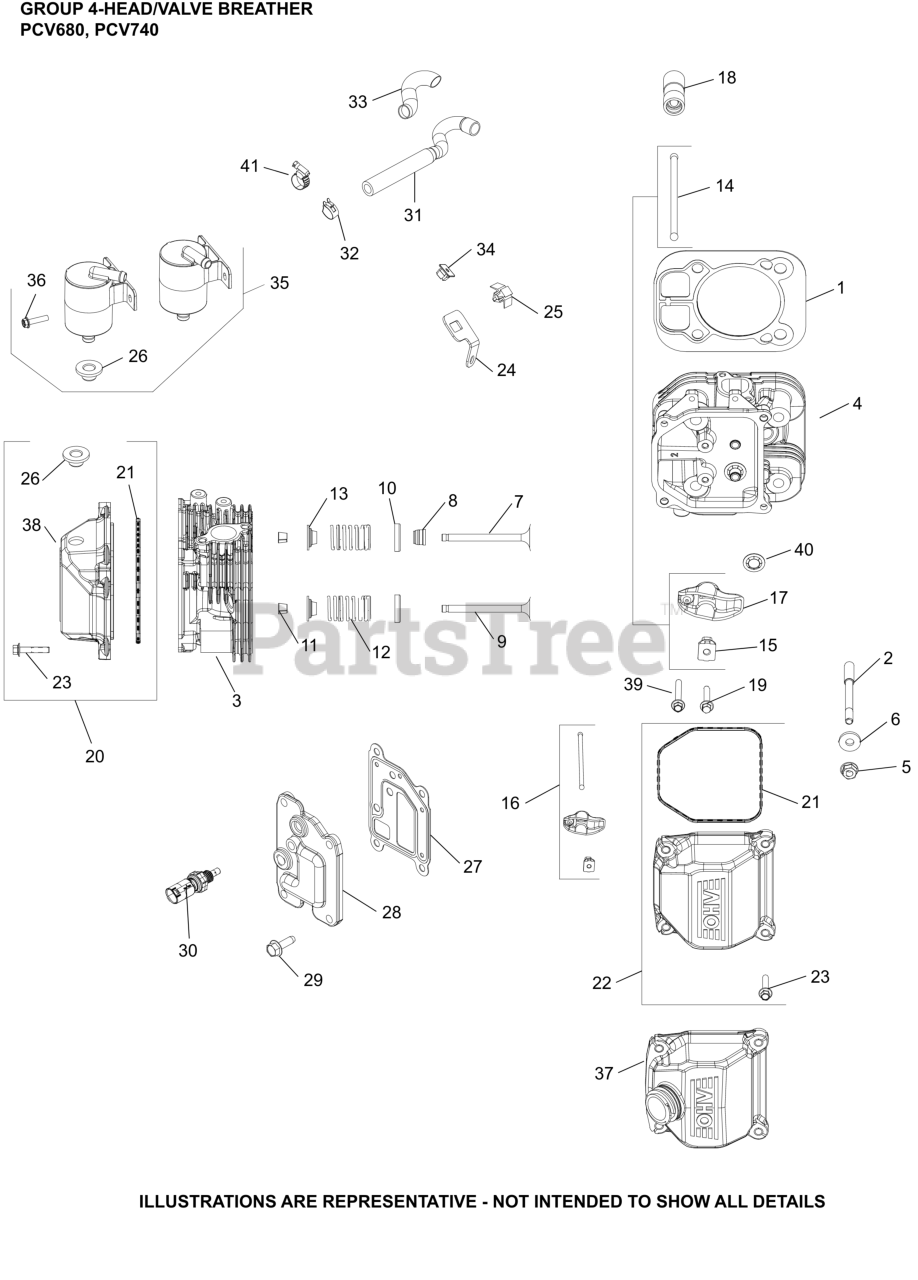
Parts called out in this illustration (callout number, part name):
1	KIT, GASKET CYLINDER HEAD
2	STUD, M8X1.25
3	KIT, CYLINDER HEAD (#1)
4	KIT, CYLINDER HEAD (#2)
5	NUT, FLG M8X1.25
6	WASHER, FLAT 8.6 MM
7	VALVE, INTAKE (STD)
7	VALVE, INTAKE (.25)
8	SEAL, VALVE BAND
9	VALVE, EXHAUST
9	VALVE, EXHAUST (.25)
10	RETAINER, SPRING
11	KIT, RETAINER
12	SPRING, VALVE
13	CAP, VALVE SPRING
14	ROD, PUSH
15	PIVOT, ROCKER ARM
16	KIT, VALVE TRAIN
17	ARM, ROCKER
18	LIFTER, VALVE HYDRAULIC-USE 25 351 11-S
20	KIT, VALVE COVER
21	O-RING (YELLOW), VALVE CO
22	KIT, VALVE COVER-PLAIN (PLASTIC)
23	SCREW, FLG M6X1.0X30
24	BRACKET, OXYGEN SENSOR
25	CLIP, O2 SENSOR
26	GROMMET, RUBBER
27	GASKET, BREATHER
28	KIT, BREATHER COVER
29	SCREW, THREAD FORMING
30	SENSOR, TEMPERATURE
31	HOSE, BREATHER
33	SLEEVE, ANTI ABRASION-USE 25 431 12-S
34	NUT, PLASTIC
35	KIT, BREATHER SEPARATOR
40	RETAINER, VALVE GUIDE (KM)
NI	SCREW, HEX FLANGE
